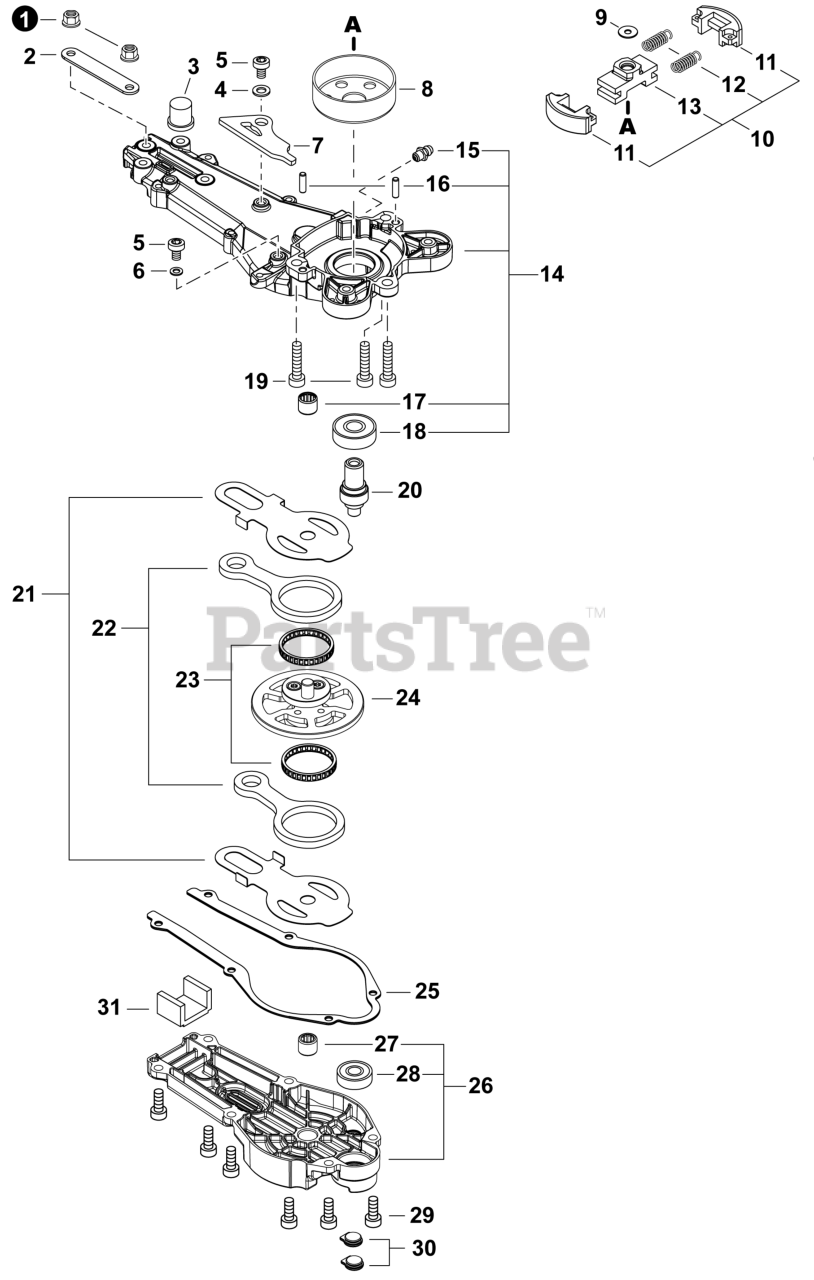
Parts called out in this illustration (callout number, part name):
1	NUT, FLANGE M5
2	PLATE, EYE
4	WASHER 5
5	BOLT, TORX 5x6
6	WASHER 5.5x12x0.8
7	CUSHION
8	DRUM, CLUTCH
9	WASHER 8
10	CLUTCH ASSY
11	SHOE, CLUTCH
12	SPRING, CLUTCH
13	HUB, CLUTCH
14	HOUSING ASSY, GEAR CASE
15	FITTING, GREASE
16	PIN, LOCATING 4x10
17	BEARING, NEEDLE 8
18	BEARING, BALL
19	BOLT, TORX 6x20
20	SHAFT, PINION
21	PLATE, SIDE
23	BEARING, NEEDLE 30
24	GEAR, SPUR
25	GASKET, GEAR CASE
26	COVER ASSY, GEAR CASE
27	BEARING, NEEDLE 8
28	BEARING, BALL 608ZZ
29	BOLT, TORX 5x16
31	PACKING, FELT
